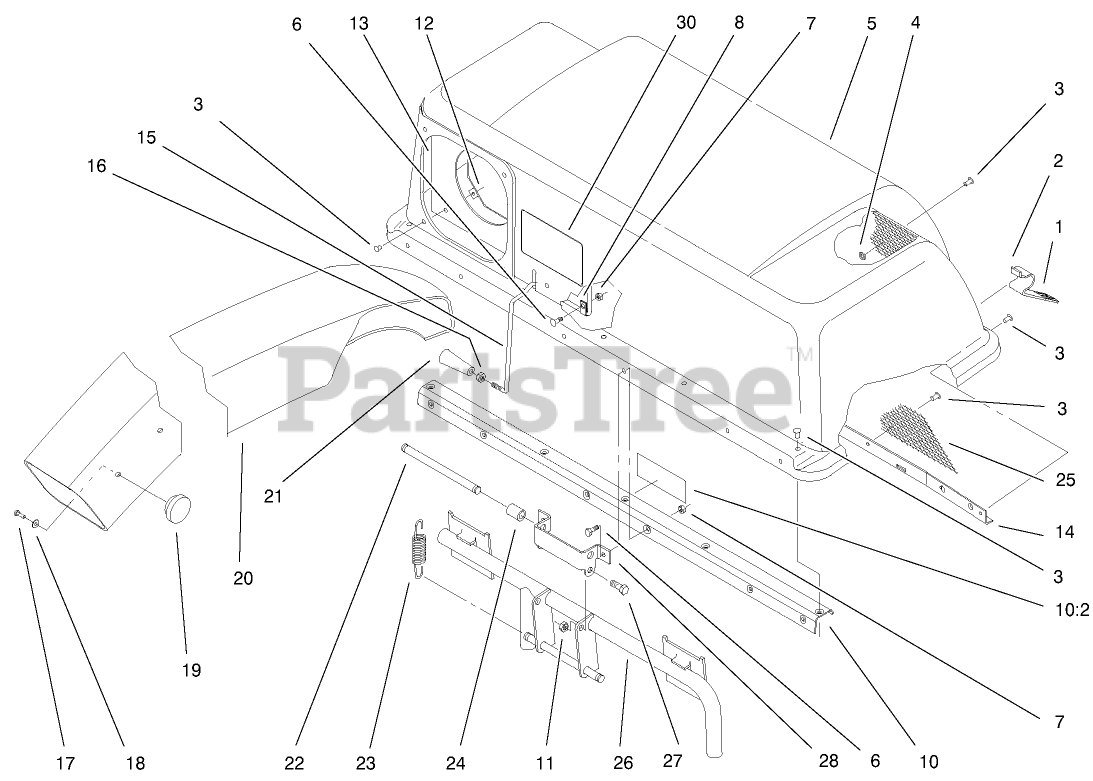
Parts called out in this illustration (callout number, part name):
2	LATCH-BAGGER, TOP
3	RIVET-BLIND
4	WASHER-FLAT
5	TOP-BAGGER
6	SCREW-HH
7	NUT-LOCK, NI
8	CLAMP
10	STIFFENER ASM
11	NUT-LOCK, NI
12	CLAMP-SEAL
13	SEAL-CHUTE
14	SUPPORT-SCREEN
15	FEELER-FILL, BAG
16	NUT-JAM
17	SCREW-PPHTF
18	WASHER-PLAIN
21	HANDLE-TAPERED
22	PIN-SPRING
23	SPRING-EXTENSION
24	SPACER
25	SCREEN-BAGGER
26	FRAME ASM
27	SCREW-HH
28	HINGE-BAG, TOP
29	DECAL-CAUTION
30	DECAL
